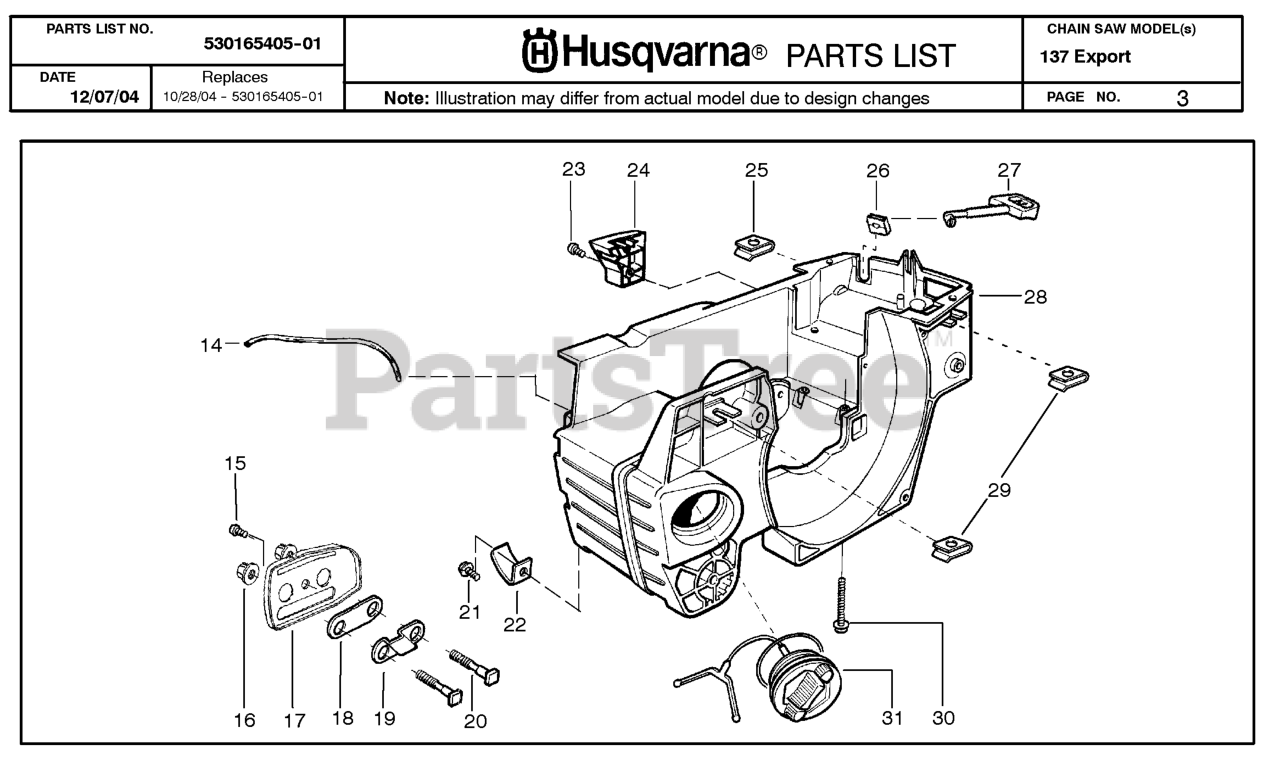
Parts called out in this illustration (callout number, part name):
14	TUBE
18	OIL TANK GASKET
19	PLATE,BAR MOUNT
20	BAR BOLT 36/41
22	CHAIN CATCHER 36/41
24	LIMITER COVER
26	CHOKE GUIDE 36/41
27	CHOKE 36/41
28	KIT ASSY CHASSIS
30	SCREW M5-0.8X35M TAP
